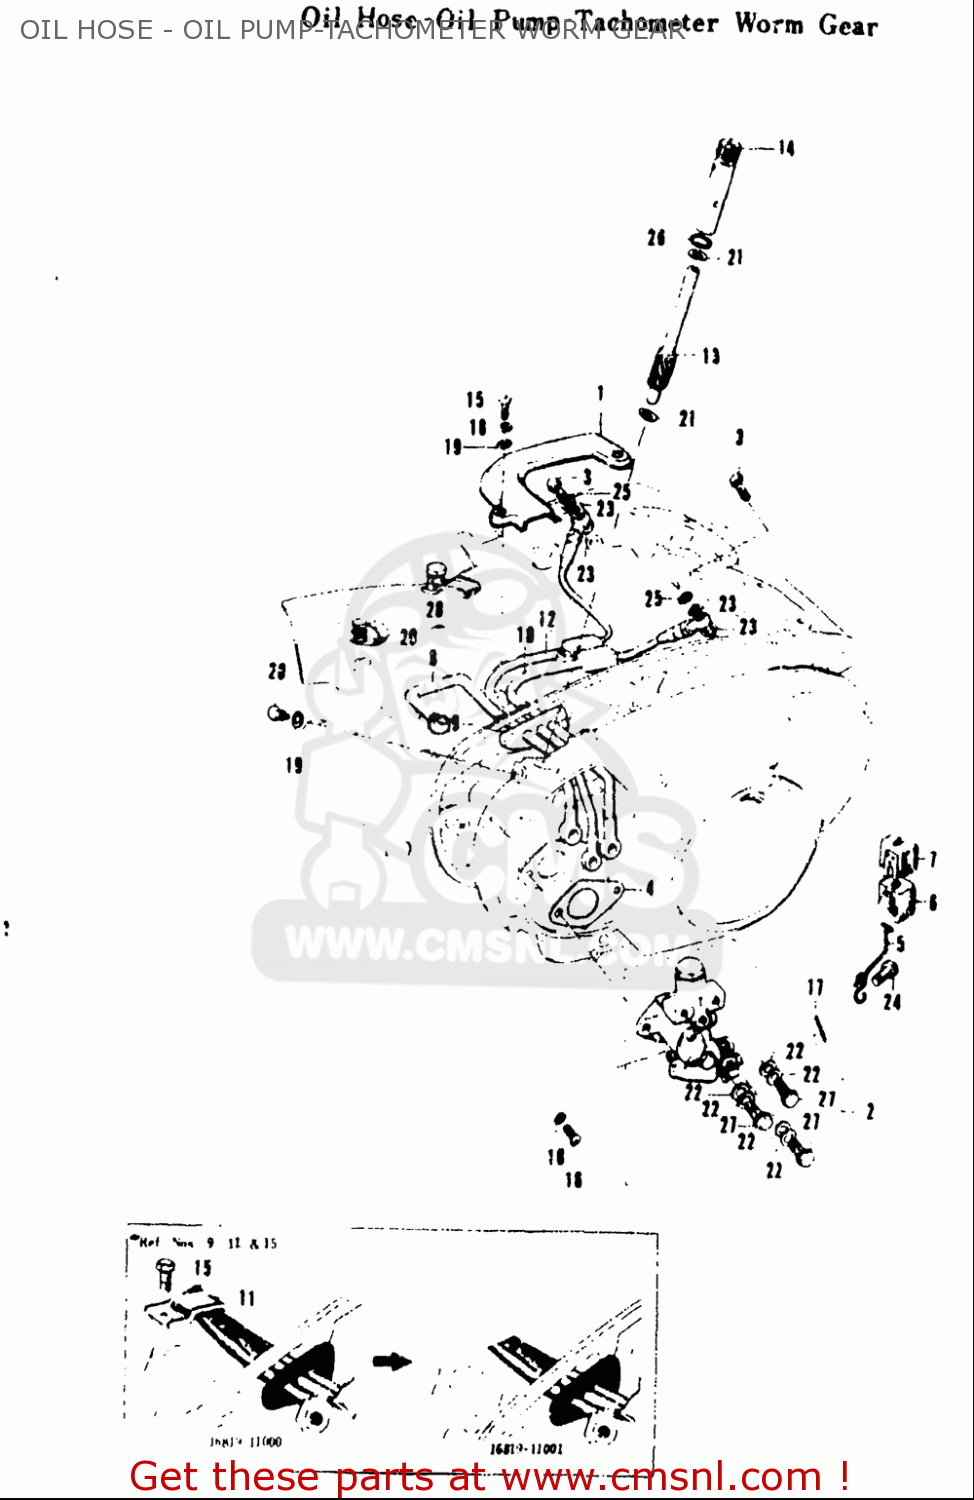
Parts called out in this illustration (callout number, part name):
5	OIL PUMP LEVER CHAIN
6	OIL PUMP LEVER CHAIN CONNECTOR
7	OIL PUMP LEVER CHAIN CONNECTOR (TC250TC250)
16	SCREW
18	WASHER,LOCK
19	WASHER
20	BOLT
21	WASHER(8X13.7X1)
22	GASKET(6.2X11X1).2 (NAS)
23	GASKET(10X16X3) (NAS)
24	OIL PUMP LEVER PIN
25	O RING(D:1.3,ID:7.6)
26	O RING(D:1.3,ID:9.6)
27	UNION BOLT
